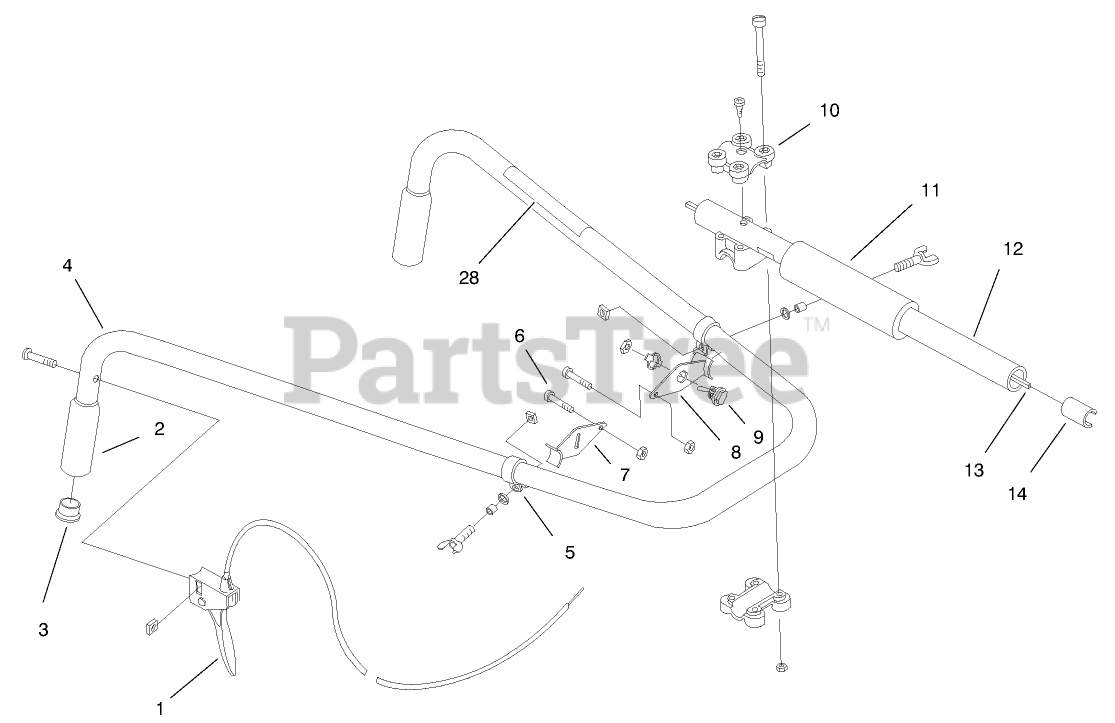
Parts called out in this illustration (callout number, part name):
2	HANDLE NITRILE GRIP
3	TUBE CLOSURE
5	ASSEMBLY - CLAMP
7	BRACKET- RH ENGINE MTG
9	SWITCH ASM
10	HANDLE BRACKET ASM
13	SHAFT - FLEXIBLE DRIVE
14	SLEEVE - RETAINER
